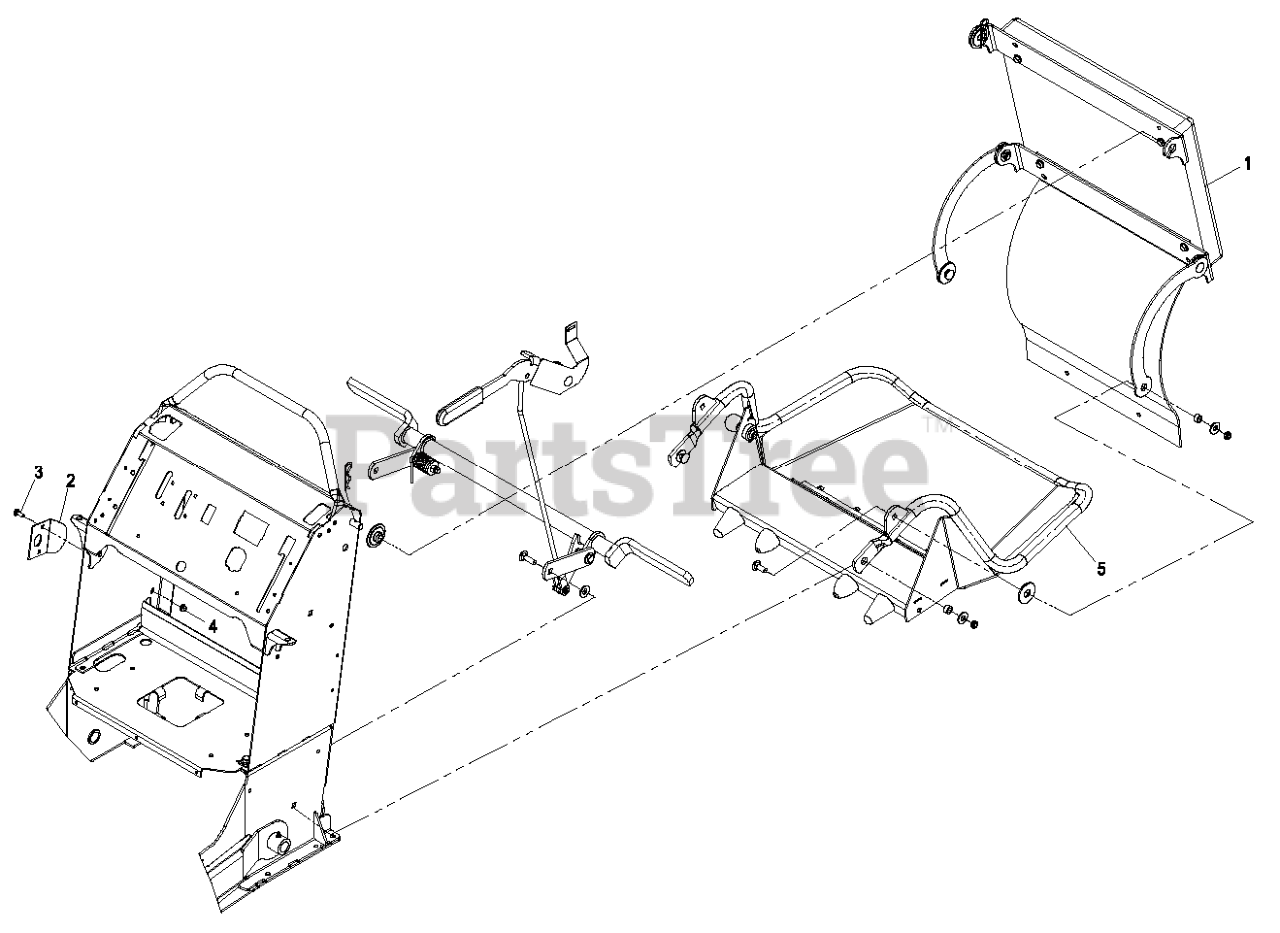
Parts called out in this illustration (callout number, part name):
2	PLATE-STRIKER
3	SCREW-CARR
5	ASM,PLATFORM
